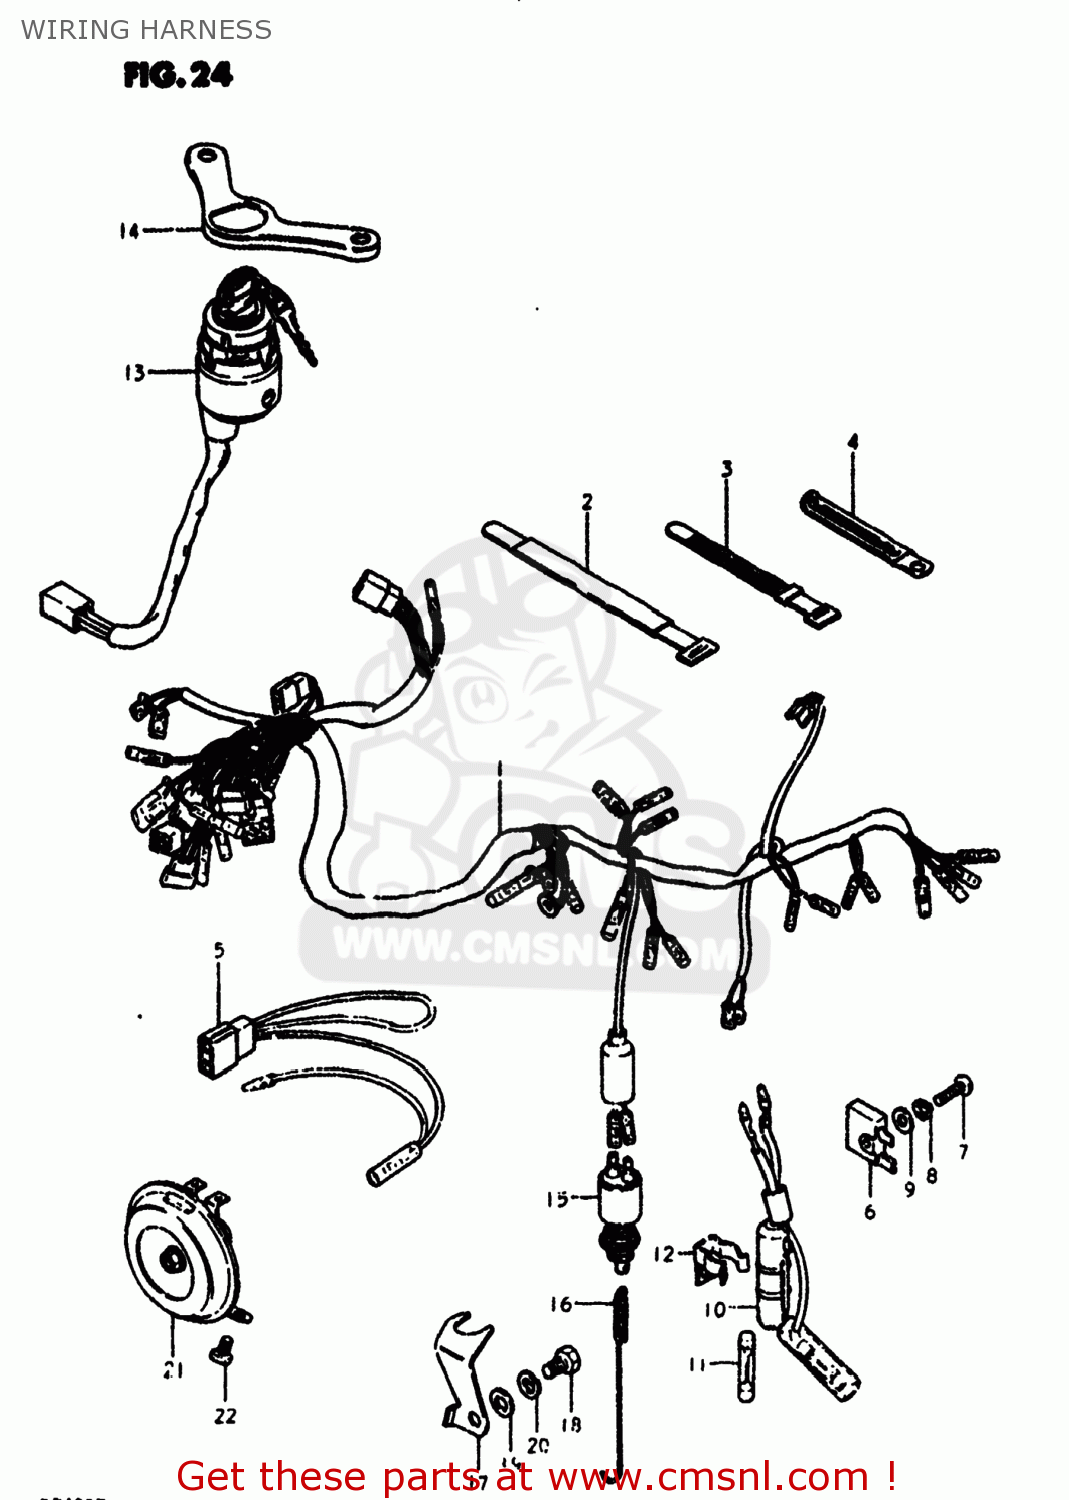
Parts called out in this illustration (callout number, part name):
1	HARNESS,WIRING
2	CLAMP
3	CLAMP(L:120)
4	CLAMP
5	WIRE
6	RECTIFIER ASSEMBLY
7	SCREW 5X20
8	LOCK WASHER
9	WASHER
10	BOX ASSEMBLY,FUSE
11	FUSE(15A)
12	HOLDER,FUSE CASE
13	SWITCH ASSEMBLY,IGNITION
14	BRACKET,IGNITION SWITCH
15	SWITCH ASSY,BRAKE LAMP
16	SPRING
17	BRACKET,STOP LAMP SWITCH
18	BOLT
19	WASHER
20	LOCK WASHER
21	HORN ASSEMBLY
22	BOLT
